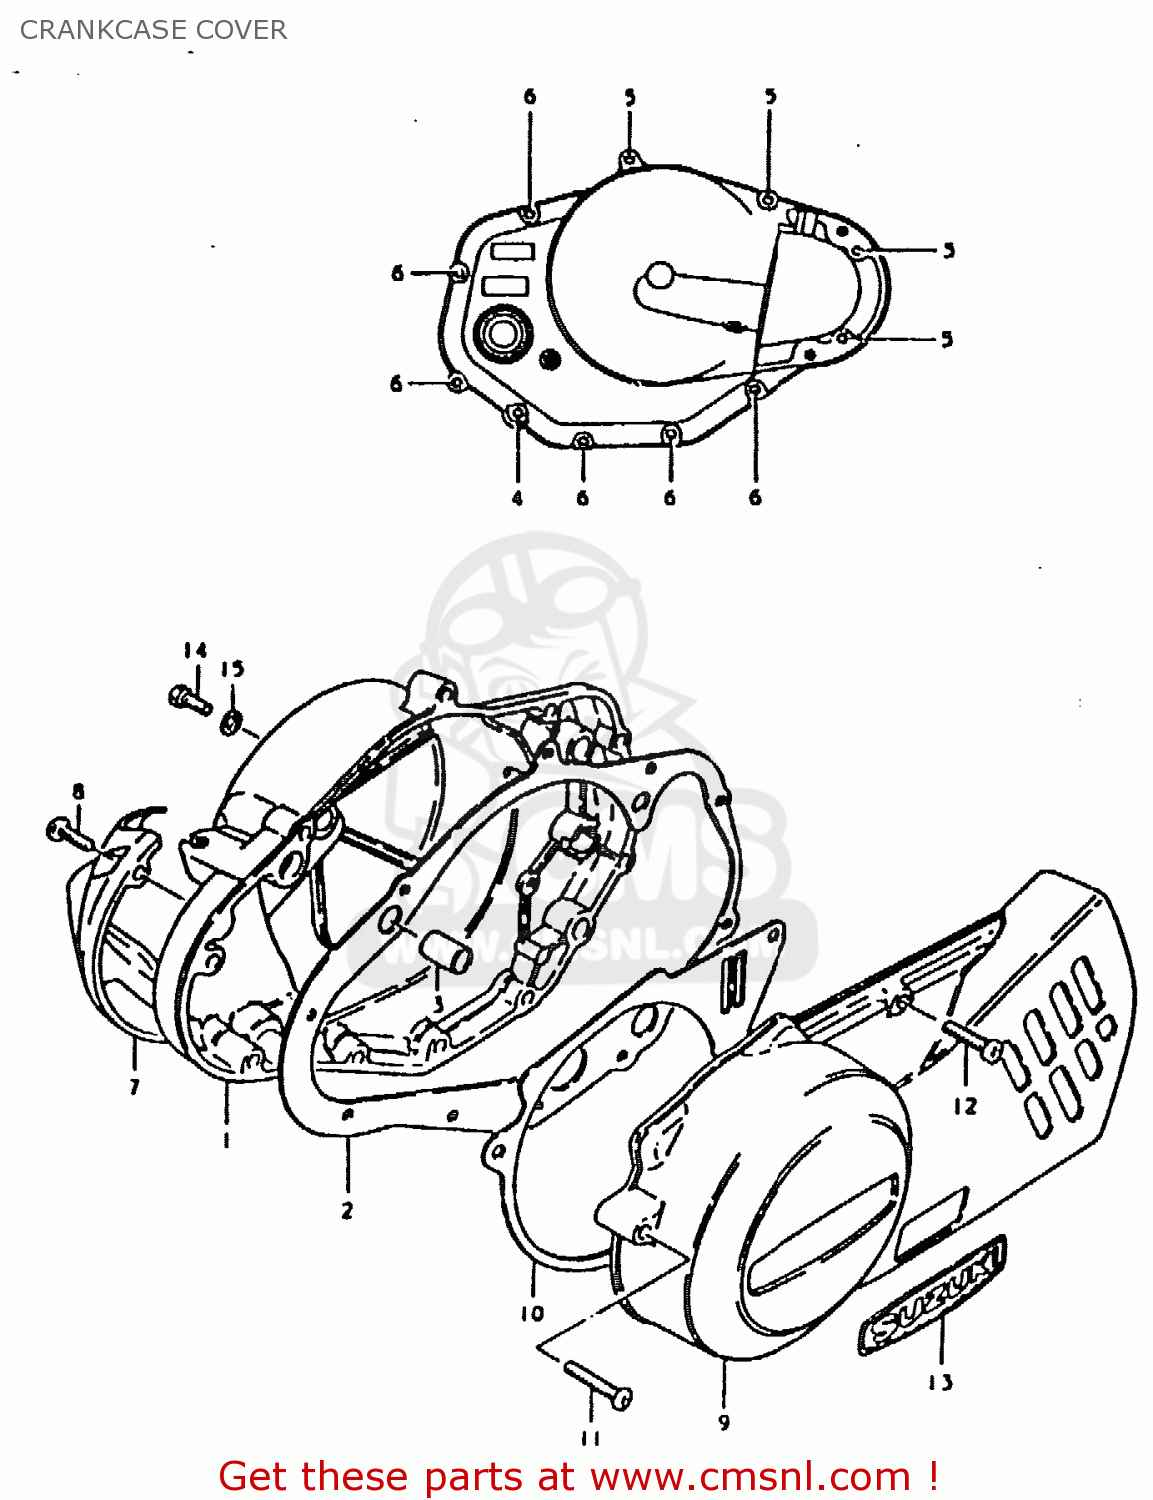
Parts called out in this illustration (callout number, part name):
1	COVER,CLUTCH
2	GASKET,CLUTCH COVER (MCA)
3	PIN
4	SCREW (6X45)
5	SCREW 6X30
6	SCREW
7	COVER,CLUTCH RELEASE ARM
8	SCREW
9	COVER,MAGNETO
10	GASKET,MAGNETO COVER (NAS)
11	SCREW 6X30
12	SCREW
13	EMBLEM,GENERATOR COVER
14	SCREW(6X10)
15	GASKET(6.2X11X1) (NAS)
